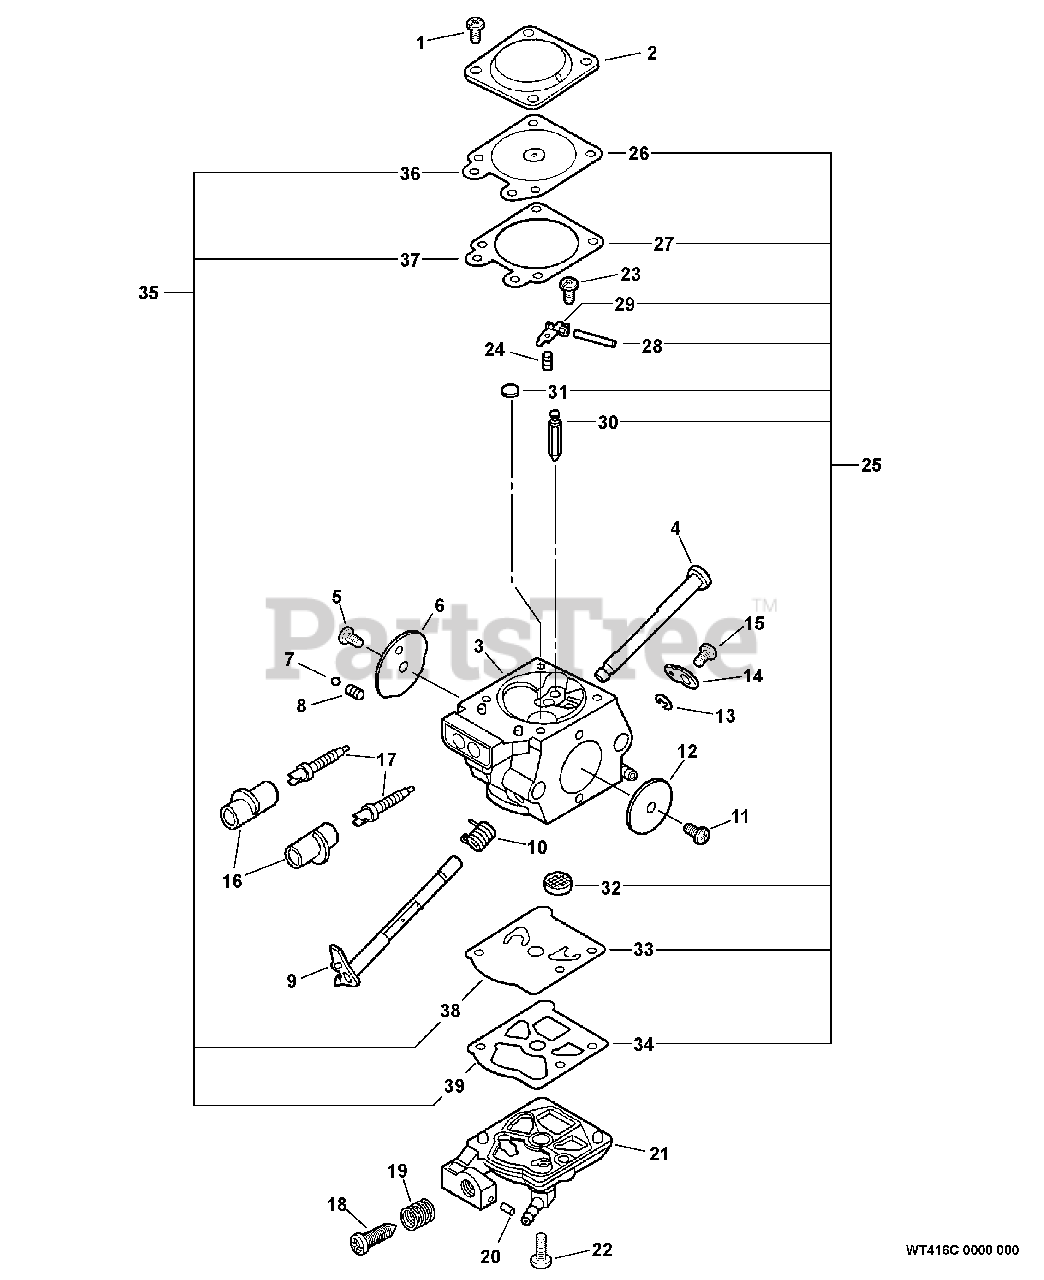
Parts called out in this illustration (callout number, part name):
2	COVER, METERING
3	BODY, CARBURETOR
4	SHAFT, CHOKE
6	VALVE, CHOKE
7	BALL, CHOKE
9	SHAFT, THROTTLE
10	SPRING, THROTTLE RETURN
12	VALVE, THROTTLE
13	RING, RETAINING
14	LEVER, THROTTLE
16	CAP, LIMITER
17	NEEDLE - MIXTURE
18	SCREW, IDLE ADJUST
19	SPRING, IDLE ADJUST
21	COVER, PUMP
22	SCREW, PUMP COVER
23	SCREW, METERING LEVER PIN
24	SPRING, METERING LEVER
25	REPAIR KIT
26	DIAPHRAGM, METERING
27	GASKET, DIAPHRAGM
28	PIN, METERING LEVER
29	LEVER, METERING
30	VALVE, INLET NEEDLE
31	PLUG, WELCH
32	STRAINER
33	DIAPHRAGM, PUMP
34	GASKET, PUMP
35	DIAPHRAGM/GASKET KIT
36	DIAPHRAGM, METERING
37	GASKET, DIAPHRAGM
38	DIAPHRAGM, PUMP
39	GASKET, PUMP
